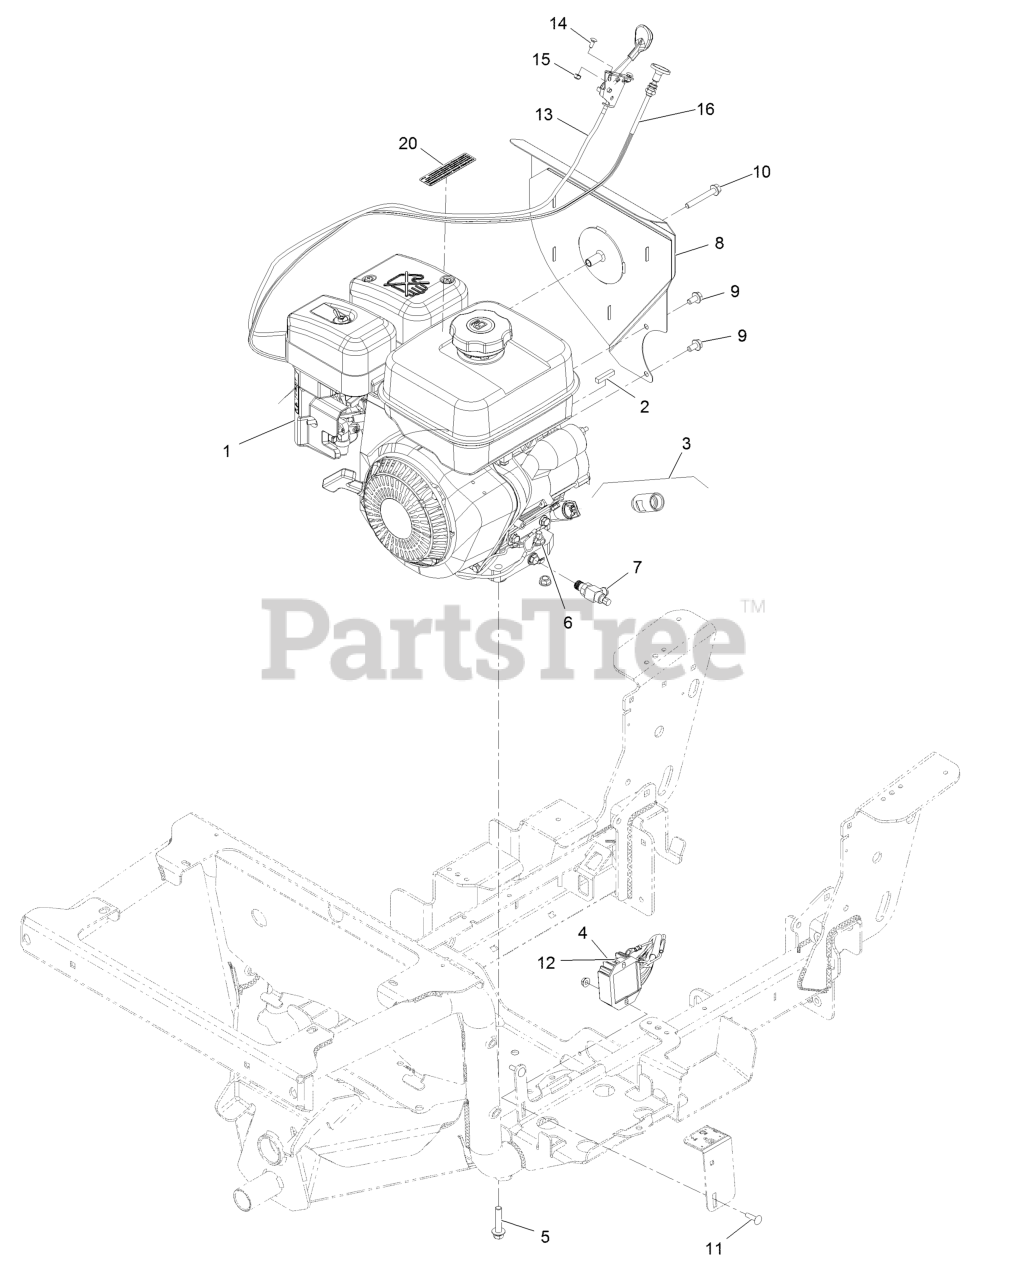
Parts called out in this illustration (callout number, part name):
2	Key-Crankshaft
3	Extender-Dipstick
4	Regulator
5	Screw-HHF
6	Nut-Hex Flg
7	Valve-Oil Drain
8	Heat Shield ASM
9	Screw-HHF, Lock
10	Screw-HHF
11	Screw-CARR
12	Nut-Hex Flg
13	Control-Throttle
14	Bolt-Carriage #10-24 X 1/2
15	Nut-Nyloc #10-24
16	Cable-Choke, Push/Pull
20	Decal-Arrester, Spark
